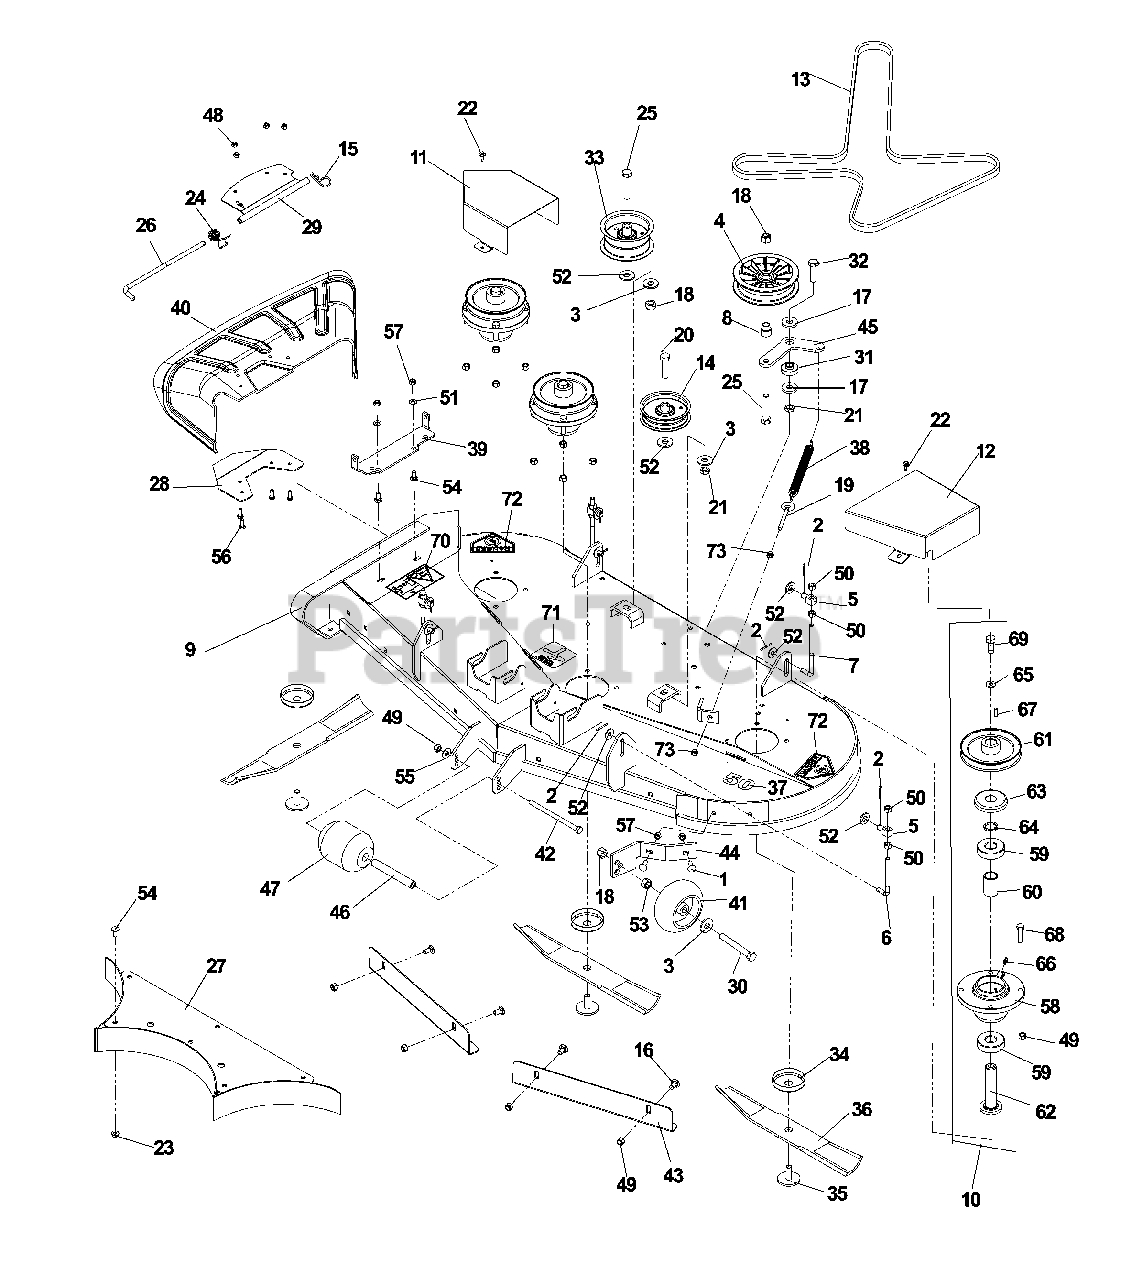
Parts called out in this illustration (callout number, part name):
1	RHSSNB 5/16C X 1.0
2	COTTER PIN 1/8 X 3/4
3	WASH USS FLAT 1/2
4	IDLER
6	L BOLT, S
7	L BOLT, L
8	SPACER - IDLER
9	DECK W/DECAL 50" RAM
10	SPINDLE, LH 6305 BRG
11	PULLEY GUARD RH BLACK
12	PULLEY GUARD LH
13	V-BELT 170" B
14	PULLEY IDLER
15	PIN, COTTER 1 3/4
16	RHSNB 3/8-16 X 3/4 GR5 ZD
17	WASHER-.533IDX1.37OD
18	NUT 1/2-13 HEX NYLOC ZD
19	EYE BOLT 5/16 X 3.50
20	BOLT 1/2-13 X 2 HH
21	NUT, 1/2-13 THIN PROF NYL
22	SCREW, TAP & DR #12-14 X 3/4
23	5/16-18 FLANGED L-NUT
24	DEFLECTOR SPRING
25	1/2-13X2-1/2 HHB GR5
26	DEFLECTOR PIN
27	W-BAFFLE WLDT.
28	DEFLECTOR BRACKET
29	DEFLECTOR MT BRKT
30	HCS 1/2-13 X 4 GR 5 ZD
31	IDLER SPACER
32	1/2-13X1-3/4 HHB GR. 5
33	IDLER PULLEY
34	TRASH GUARD
35	BLADE BOLT
36	BLD 50`HI LIFT FUSION
37	DECAL, DECK 50"
38	SPRING, DECK BELT
40	44 DEFLECTOR
41	GUAGE WHEEL
42	BOLT 3/8 X 6 GR5
43	BLOW-BY BAFFLE
44	BRACKET
45	IDLER ARM
46	BUSHING
47	ROLLER 3-3/4 DIA. X 4-1
48	NUT 1/4-20 NYLOC
49	NUT 3/8-16 NYLOC
50	NUT 7/16C HEX
51	FLAT WASHER 5/16 SAE
52	WASHER 1/2" FLAT
53	NUT HEX 1/2
54	BOLT 5/16C X 3/4" CARRIAGE
55	WASHER 3/8 FLAT
56	HCS 1/4C X 3/4 HCS
57	NUT 5/16 NYLOC
58	DECK HUB MACHINED
59	BEARING - 6305 - 2RS
61	METRIC PULLEY
62	SHAFT SHORT
63	TRASH GUARD
64	HUB PULLEY SPACER
65	WASHER .525 X 1.375 X .25
66	ZERK, 3/16, DRIVE IN
67	OUTER SHAFT KEY
68	HHB 3/8-16X1-1/2 GR5
69	1/2-20 UNF X 1 1/4 HHBLT
70	DECAL, EURO SEVERING
71	DECAL, BELT ROUTING (18656)
72	DECAL, CPSC
73	NUT 5/16C WHIZ
